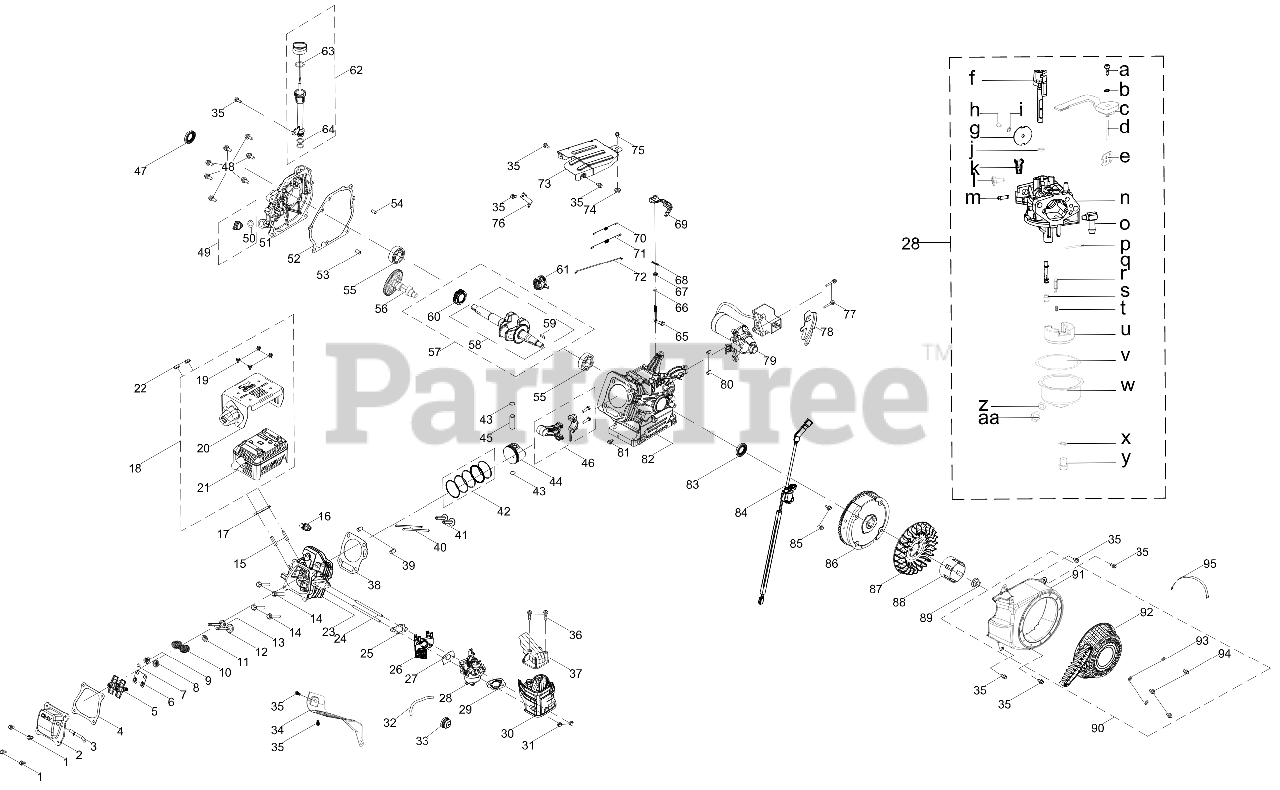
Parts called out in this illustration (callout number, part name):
1	BOLT M6 x 16
2	VALVE COVER
3	BREATHER HOSE
4	VALVE COVER GASKET
5	ROCKER ARM ASSEMBLY
6	ROCKER ARM BASE
7	EXHAUST VALVE ADJUSTER
8	INTAKE VALVE SPRING RETAINER
9	EXHAUST VALVE SPRING RETAINER
10	VALVE SPRING
11	INTAKE VALVE SEAL
12	INTAKE VALVE
13	EXHAUST VALVE
14	BOLT M8-1.25 x 55 GR10.9
15	STUD M8 x 36
16	SPARK PLUG
17	MUFFLER GASKET
18	MUFFLER ASSEMBLY
19	BOLT M5-.8 x 8 CL10.9
20	OUTER MUFFLER SHIELD
21	MUFFLER ASSEMBLY
23	CYLINDER HEAD
24	STUD M6-1 x 110 GR8.8
25	CARBURETOR INSULATOR GASKET
26	CARBURETOR INSULATOR
27	CARBURETOR GASKET
28	CARBURETOR
29	CARBURETOR GASKET PLATE
30	HEATER BOX HOUSING
32	FUEL HOSE 3.2X6.5X530
34	AIR SHIELD
35	BOLT M6-1 x 12 GR8.8
36	BOLT M4.2 x 16
37	INTAKE HEATER BOX
38	CYLINDER HEAD GASKET
40	PUSH ROD
42	PISTON RING SET
43	PISTON PIN SNAP RING
45	PISTON PIN
46	CONNECTING ROD ASSEMBLY
47	OIL SEAL
48	BOLT M8-1.25 x 32 GR5.8
50	O-RING 15.8 x 2.5
51	CRANKCASE COVER
52	CRANKCASE COVER GASKET
53	DOWEL PIN
54	DOWEL PIN
57	CRANKSHAFT ASSEMBLY
58	CRANKSHAFT
59	FLYWHEEL KEY
60	DRIVE TIMING GEAR
61	GOVERNOR GEAR/SHAFT ASSEMBLY
62	DIPSTICK ASSEMBLY
63	DIPSTICK O-RING
64	OIL FILL TUBE O-RING
65	GOVERNOR SHAFT
67	GOVERNOR SEAL
68	COTTER PIN
69	GOVERNOR LEVER
70	GOVERNOR SPRING
71	THROTTLE RETURN SPRING
72	GOVERNOR ROD
73	GOVERNOR SHIELD
75	BOLT-M6-1 x 28 GR8.8
76	GOVERNOR SPRING BRACKET
77	BOLT M6-1 x 32 GR8.8
78	LOWER SHIELD
79	ELECTRIC STARTER
80	DOWEL PIN
81	DRAIN BOLT M10 x 1.25
82	CRANKCASE
83	OIL SEAL
84	IGNITION COIL ASSEMBLY
85	BOLT M6-1 x 25 GR8.8
86	FLYWHEEL
87	COOLING FAN
88	STARTER CUP
89	FLYWHEEL NUT
90	RECOIL HOUSING ASSEMBLY
91	BLOWER HOUSING
92	RECOIL STARTER HOUSING
93	RECOIL FLAT WASHER
94	BOLT M6 x 10
95	CABLE TIE - 3 x 150
